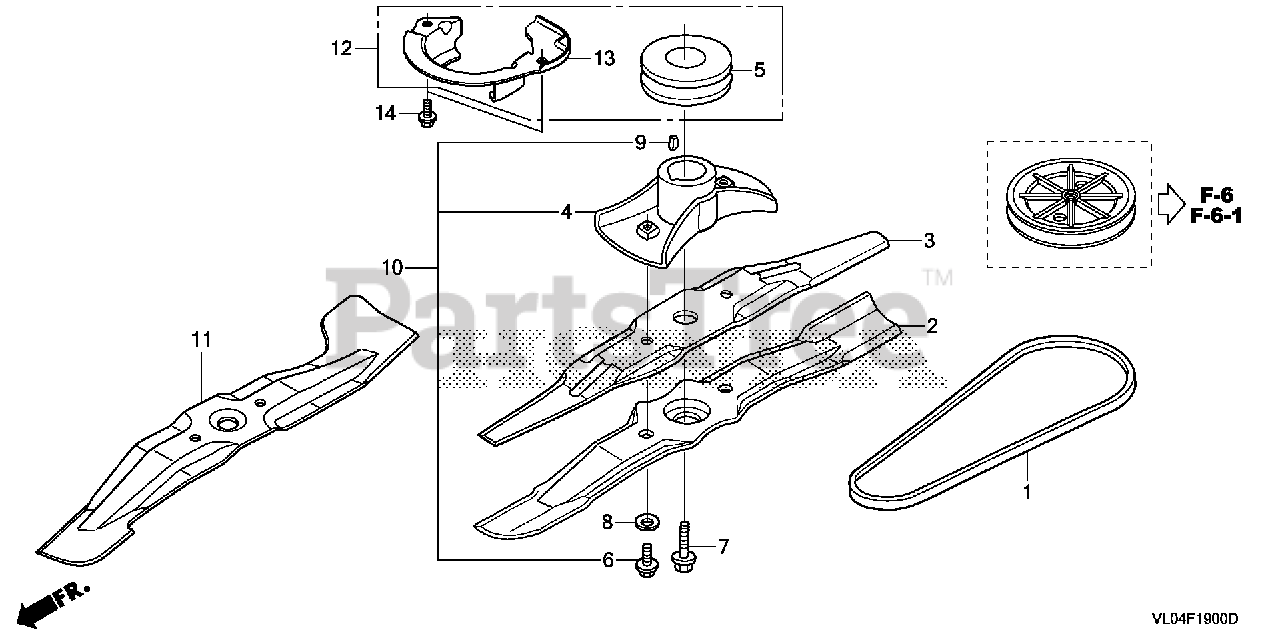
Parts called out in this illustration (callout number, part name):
2	BLADE, ROTARY
3	BLADE, ROTARY (UPPER) (PCD=88MM)
4	HOLDER, BLADE
6	BOLT, HEX. (10X25)
7	BOLT, FLANGE (3/8-24X1")
8	WASHER, SPRING (10MM)
9	KEY, WOODRUFF (3/16X5/8)
10	HOLDER KIT, BLADE
